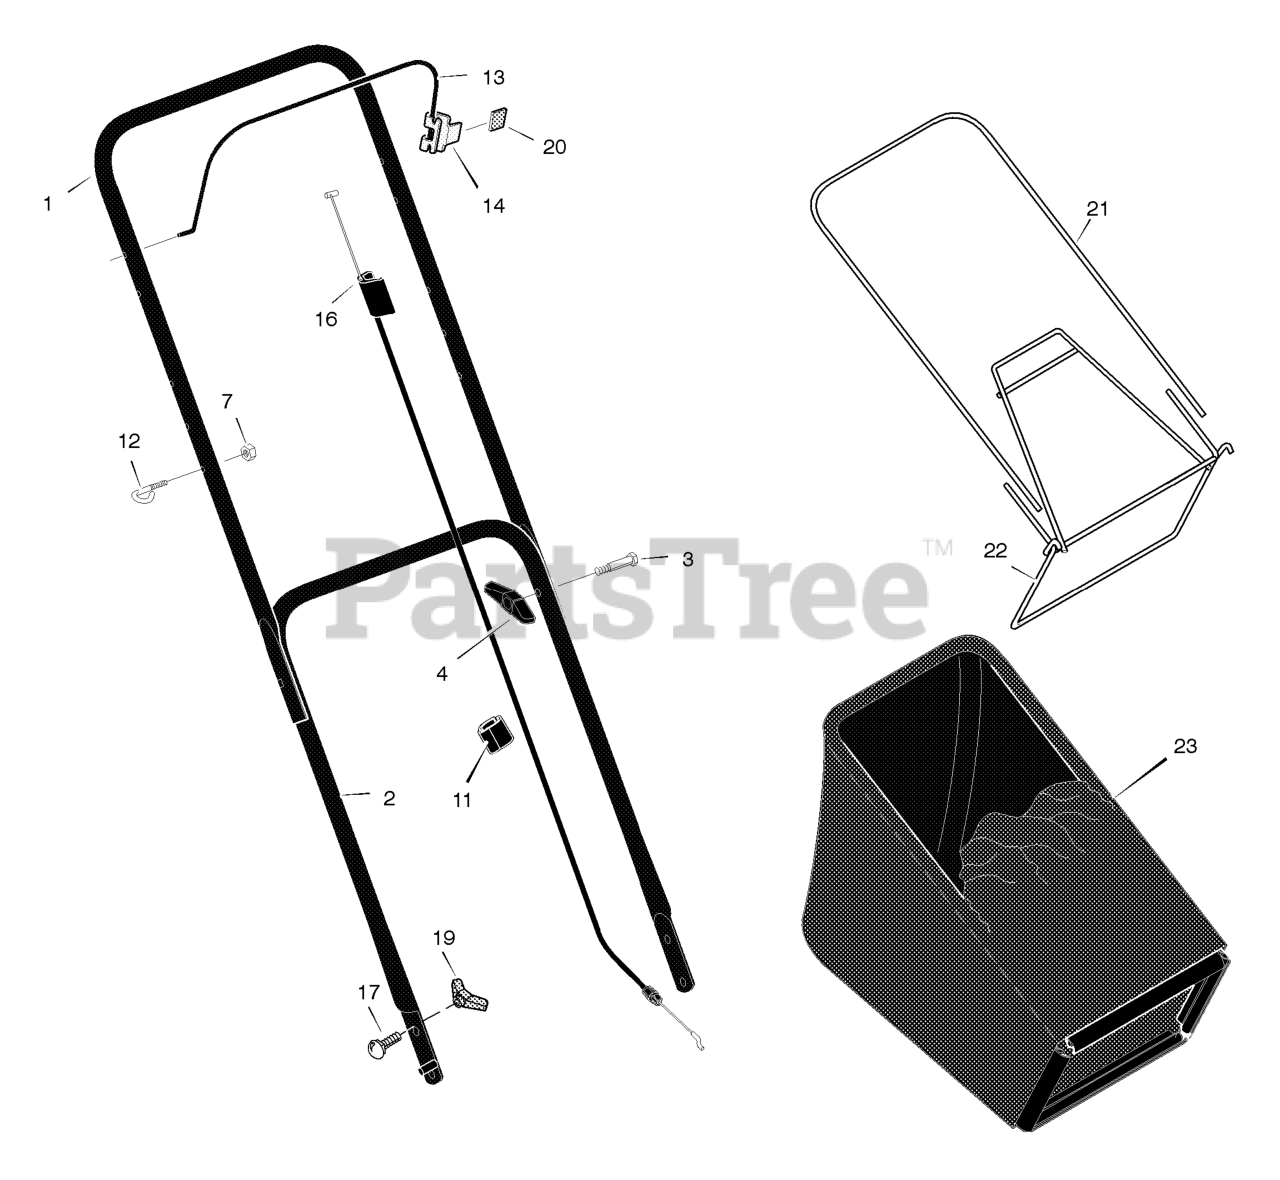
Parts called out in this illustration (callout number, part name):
1	Handle, Upper (Gray)
2	Handle, Lower (Gray)
4	Knob, Plastic
7	Locknut
11	Clip, Cable
12	Guide, Rope
13	Engine Stop Lever
14	Bracket, Stop Lever
16	Engine Stop Cable
17	Bolt, Carriage
19	Knob, Plastic
20	Sleeve, Vinyl
21	Frame, Top
22	Frame Assembly
23	Bag, Cloth
